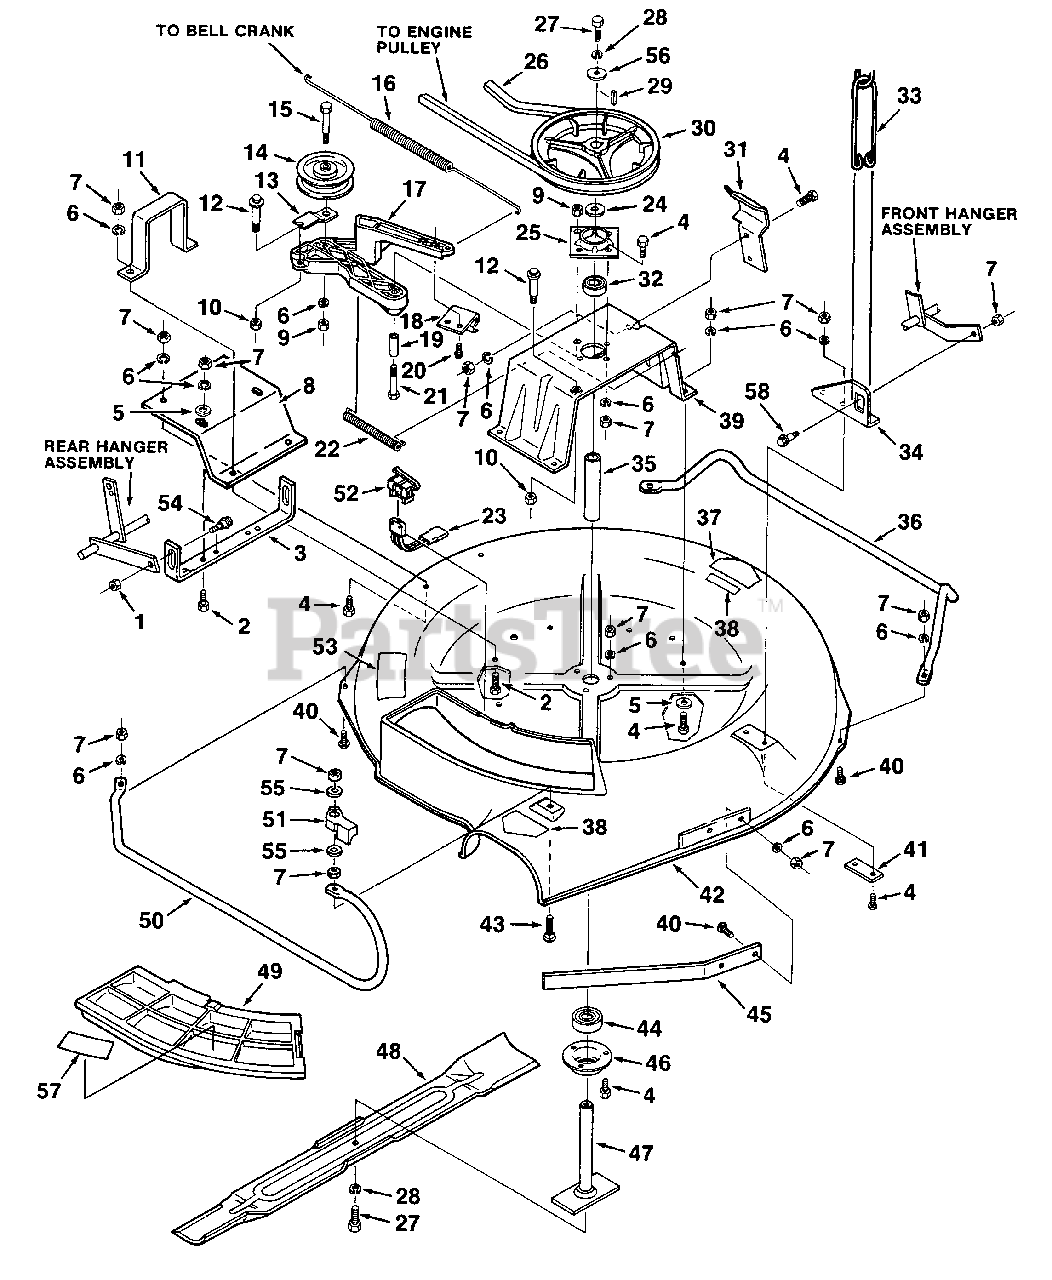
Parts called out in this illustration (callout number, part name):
1	NUT- 5/16-18 hex c/lock
2	SCREW- 1/4-20 x 7/8 hex
3	BRACKET- Rear deck lift
4	SCREW- 1/4-20 x 5/8 hex
5	WASHER- Flat
6	WASHER- Lock 1/4 hvy
7	NUT- 1/4-20 hex c/lock
8	SUPPORT- Rear lift bracket
9	NUT- 3/8-16 hex centerlock
10	NUT- 3/8-24 hex c/lock
11	GUIDE- Arm
12	BOLT- Shoulder
13	PLATE- Wear
14	PULLEY- Idler
15	SCREW- 3/8-16 x 2 1/2 hex
16	SPRING- PTO clutch
17	ARM- Cutter clutch
18	BRACKET- Brake
19	SPACER- Arm
22	SPRING- PTO brake
25	RETAINER- Bearing
26	BELT- Cutter
27	SCREW- 3/8-24 x 1 hex
28	WASHER- Lock 3/8 hvy
29	KEY- 3/16-1
30	PULLEY- Spindle
31	GUIDE- Brake
32	BEARING- Spindle
33	LINK- Lower Lift
34	BRACKET- Front deck lift
35	SPACER- Spindle
36	BAR- Skid L H
37	DECAL- CPSC warning
38	DECAL- No-step
39	BRACKET- Spindle
40	SCREW- 1/4-20 x 5/8 sq neck carr
41	PLATE- Back up
42	HOUSING- Cutter
44	BEARING- Spindle
45	GUARD- Toe
46	RETAINER- Bearing lower
47	SPINDLE & ADAPTER ASSY
48	BLADE- Cutter 30"
49	COVER- Plate
50	BAR- Skid R H
51	LATCH- Retaining
52	BRACKET- Switch
53	DECAL- Danger
54	BOLT- Shoulder
55	WASHER
58	BOLT- Shoulder
